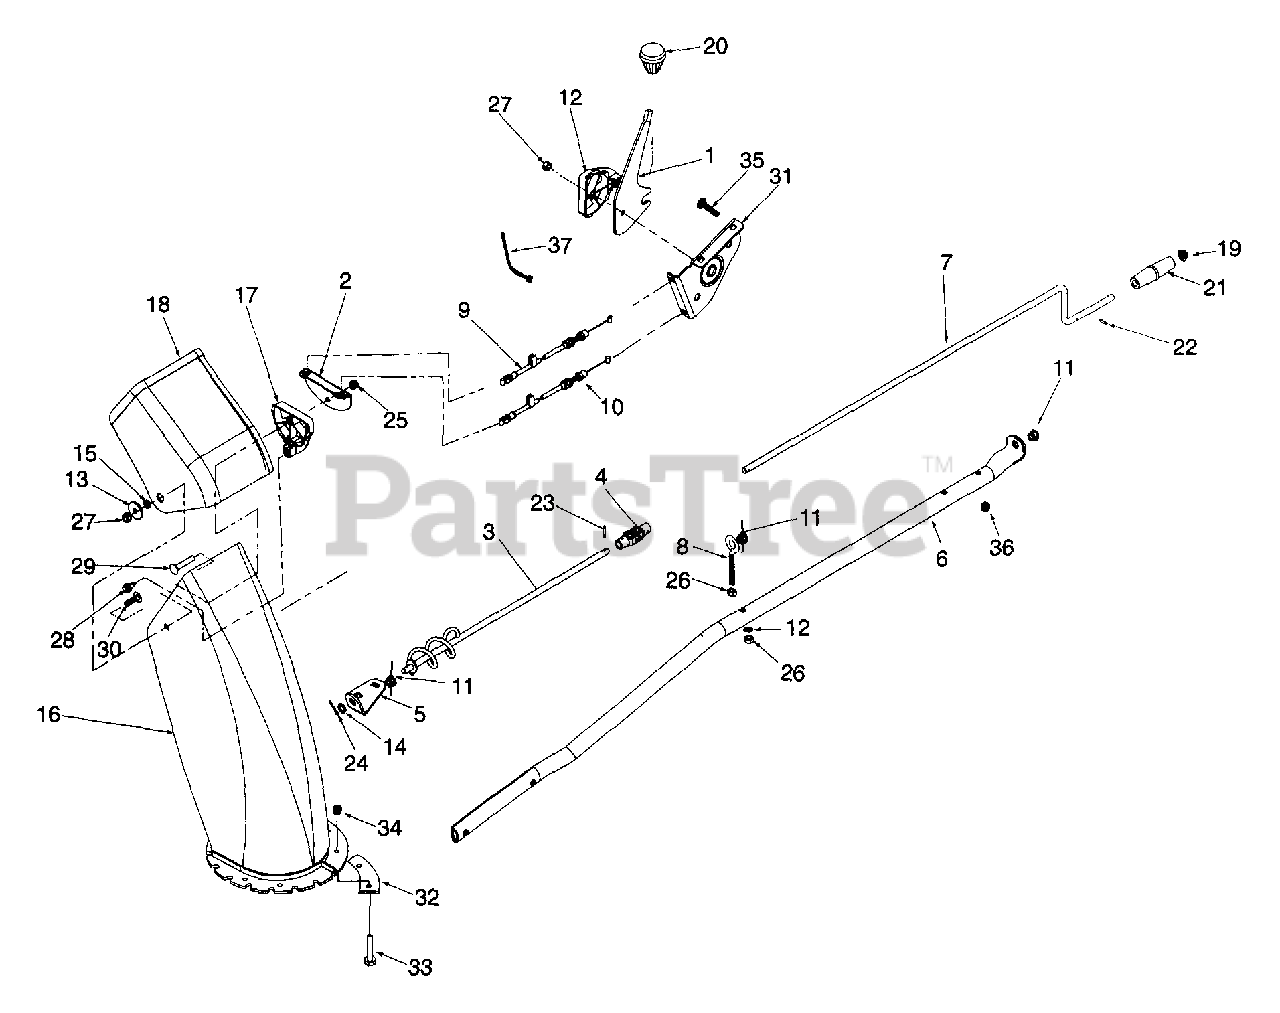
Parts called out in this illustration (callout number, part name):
1	Hndl:Tilt:Chute
3	Chute Crank Assy.18.0 Lg. - RH
4	Block Ass'y: Joint
5	Chute Crank Bracket
8	Eye Bolt 5/16-18 x 3.0 Lg.
9	Cable:Chute:w/Culp, 66 Lg.
10	Cable:Chute 66 Lg.
11	Plastic Bushing .380 I.D.
12	Wash:Belvl:.340 I.D. x .872 O.D.
13	Wash:Fl:.344 I.D.:1.125 O.D.:.12
14	Fl. Wash .385 I.D. x .62 O.D. x .06
15	Spcr:Chut:Pivot
16	Chut:.:Extended 6" Dia.
17	Gde:Cable:Chute Tilt
18	6" Dia. Upper Chute
19	Cap:Push x 3/8 Rod
20	Knob:Shift:1.60 O.D. x 1.56
21	Knob:Crk:1.00 Dia. x 3.2 Chute
22	Pin:Roll:1/8 O.D.:.63
23	Spiral Pin - 1/8 Dia. x .812 Lg.
24	Pin:Cot: 3/32 x .750
25	Nut:Hx.: 5/16-18:Gr.C:Lock
26	Hx. Nut:5/16-18:Gr.A:
27	Nut:Lock:5/16-18:Cen.
28	Scr:1/4-14:. 625: Hx Ind Wsh
29	Carriage Bolt 5/16-18 X 1.75
30	Scr:Carr:5/16-18:1.00
31	Asm:Chute Tilt Brkt
32	Chute Flange Keeper
33	Hx. Bolt 1/4-20:.75 Lg.
34	Hx. Flg. Nut 1/4-20
35	Carr. Bolt 5/16-18:1.50 Gr.2
36	Nut-Lock 5/16-18 Gr.5
37	Cable Tie
